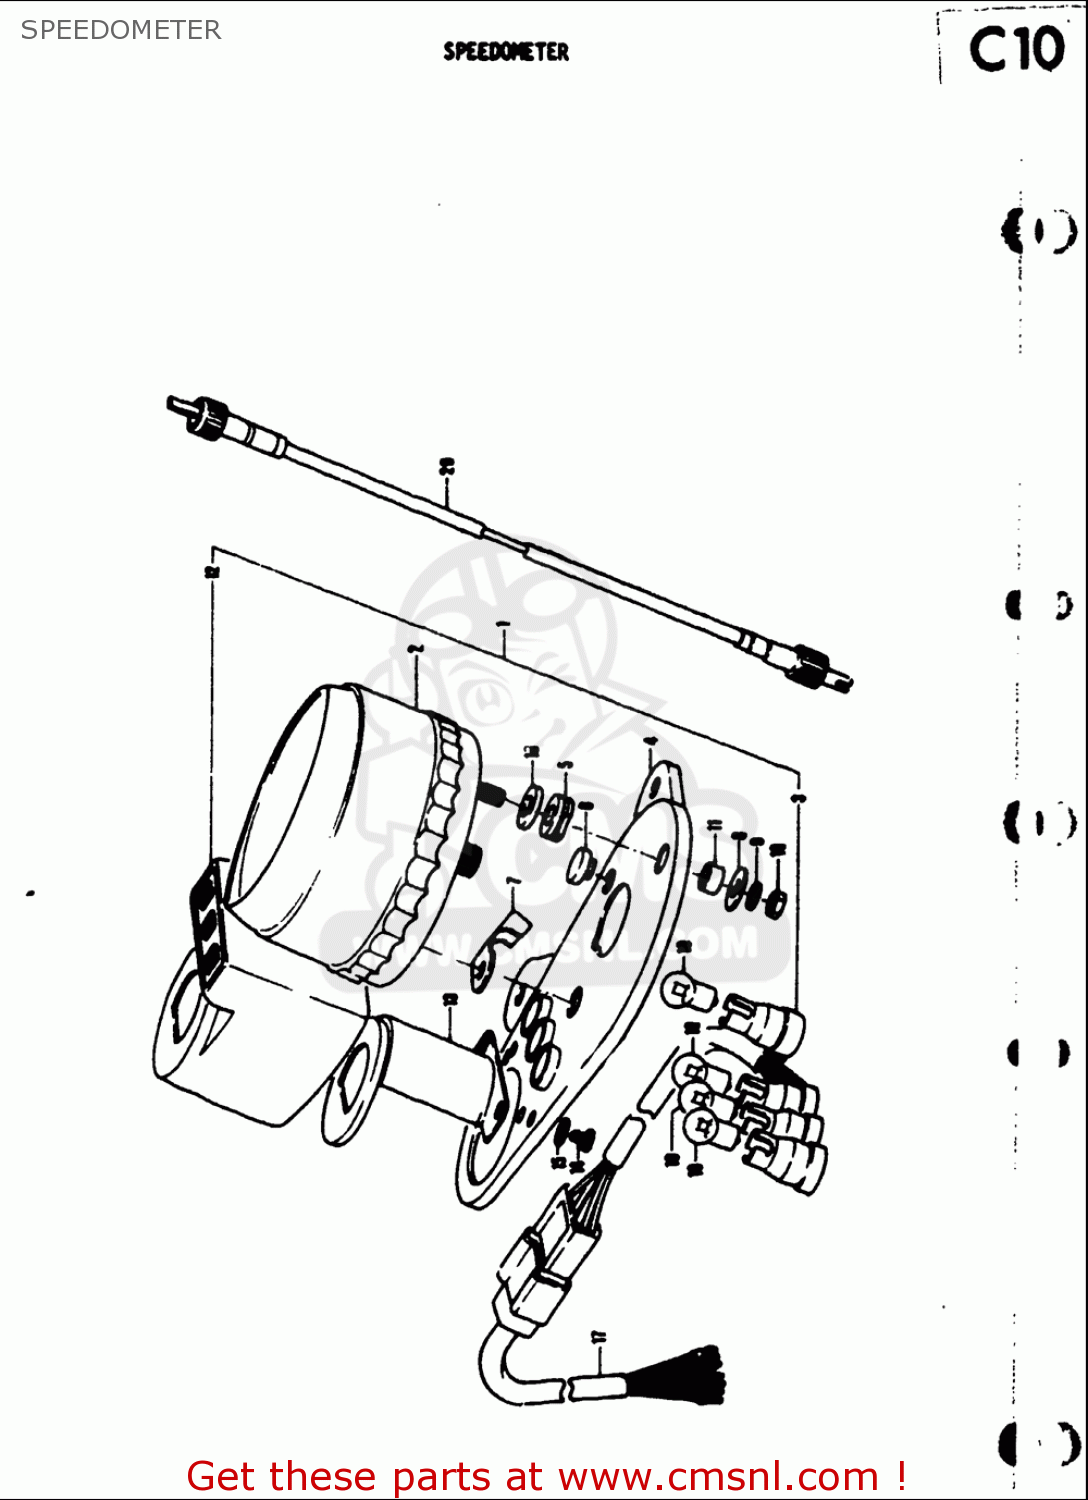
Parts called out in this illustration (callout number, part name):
8	WASHER(5.5X16X1.2)
9	WASHER,LOCK
10	NUT
11	SPACER,METER
14	SCREW
15	WASHER,LOCK
18	BULB(6V/3W)
19	BULB(6V1.7W,STANLEY,A61A)
20	CABLE ASSY,SPEEDOMETER
